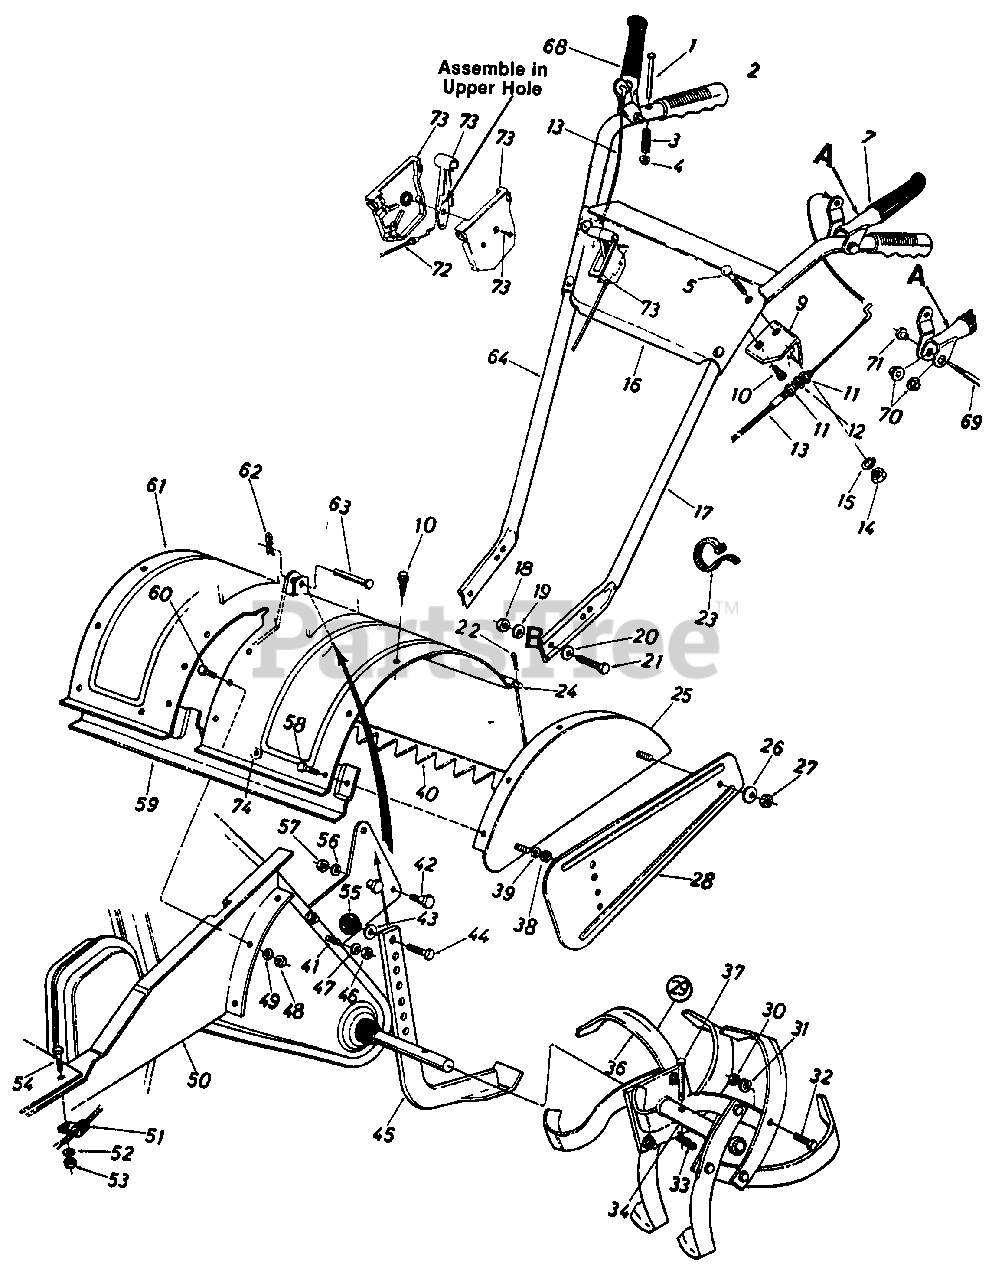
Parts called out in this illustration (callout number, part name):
1	Clevis Pin 1/4" Dia. x 2.25"
2	G rip
3	Compression Spring .33" O.D. x 1.2" Lg.
4	Cap Speed Nut 1/4" Rod
5	Carr. Bolt 5/16-18 x 1.75"
7	Clutch Grip Ass'y.-L.H.
9	Clutch Cable Bracket
10	Hex Wash. S-Tap Scr. 5/16-18 x .62" Lg.
11	Hex Nut 5/16-24 Thd.
12	L-Wash. 5/16" I.D.
13	Clutch Control Cable
14	Hex Nut 5/16-18 Thd.
15	L-Wash. 5/16" I.D.
16	Handle Panel
19	L-Wash. 3/8" I.D.
20	Bell-Wash. 3/8" I.D.
21	Hex Bolt 3/8-16 x 1.00" Lg.
22	Cotter Pin 3/32" Dia. x 3/4"
24	Tiller Flap Rod
27	Hex Nut 5/16-18 Thd.
28	Side Shield
29	Tine Ass'y. Comp.-L.H.
30	Hex Nut 3/8-24 Thd.
31	L-Wash. 3/8" I.D.
32	Hex Bolt 3/8-24 x 1.25" Lg.
33	Hairpin Cotter
34	Tine Adapter Ass'y.
38	Hex Nut 5/16-18 Thd.*
39	L-Wash. 5/16" I.D.*
40	Tine Shield Flap
41	Hex Bolt 5/16-18 x 1.0" Lg.*
42	Shld. Bolt 1/2" Dia. x .426"
43	Fl-Wash. 3/8" I.D. x 5/8" O.D.
44	Hex Bolt 3/8-16 x 314" Lg.*
46	Hex Nut 5/16-18 Thd.*
47	L-Wash. 5/16" I.D.*
48	Hex Nut 5/16-18 Thd.*
49	L-Wash. 5/16" I.D.*
50	Frame Rail-L.H.
51	Clamp 5/16" Dia.
52	L-Wash. 5/16" I.D.*
53	Hex Nut 5/16-18 Thd.*
54	Hex Bolt 5/16-18 x 314" Lg.*
55	Ball Knob 1-1/4" Dia. x 3/8-16 Thd.
56	L-Wash. 3.8" I.D.*
57	Hex Nut 3/8-16 Thd.*
58	Hex Bolt 5/16-18 x .75" Lg.*
59	Bracket Reinforcement
60	Hex Bolt 5/16-18 x .75" Lg.*
61	Tine Shield Ass'y.
62	Hairpin Cotter
63	Clevis Pin 3.8" Dia.
69	Shoulder Bolt .38" Dia. x 1.53" Lg.
70	Hex Flange Plastic Bearing
71	Shoulder Nut 1/4-20 Thd.
72	Throttle Control Wire
73	Throttle Control Box Ass'y.
74	Bell-Wash. 5/16" I.D.
